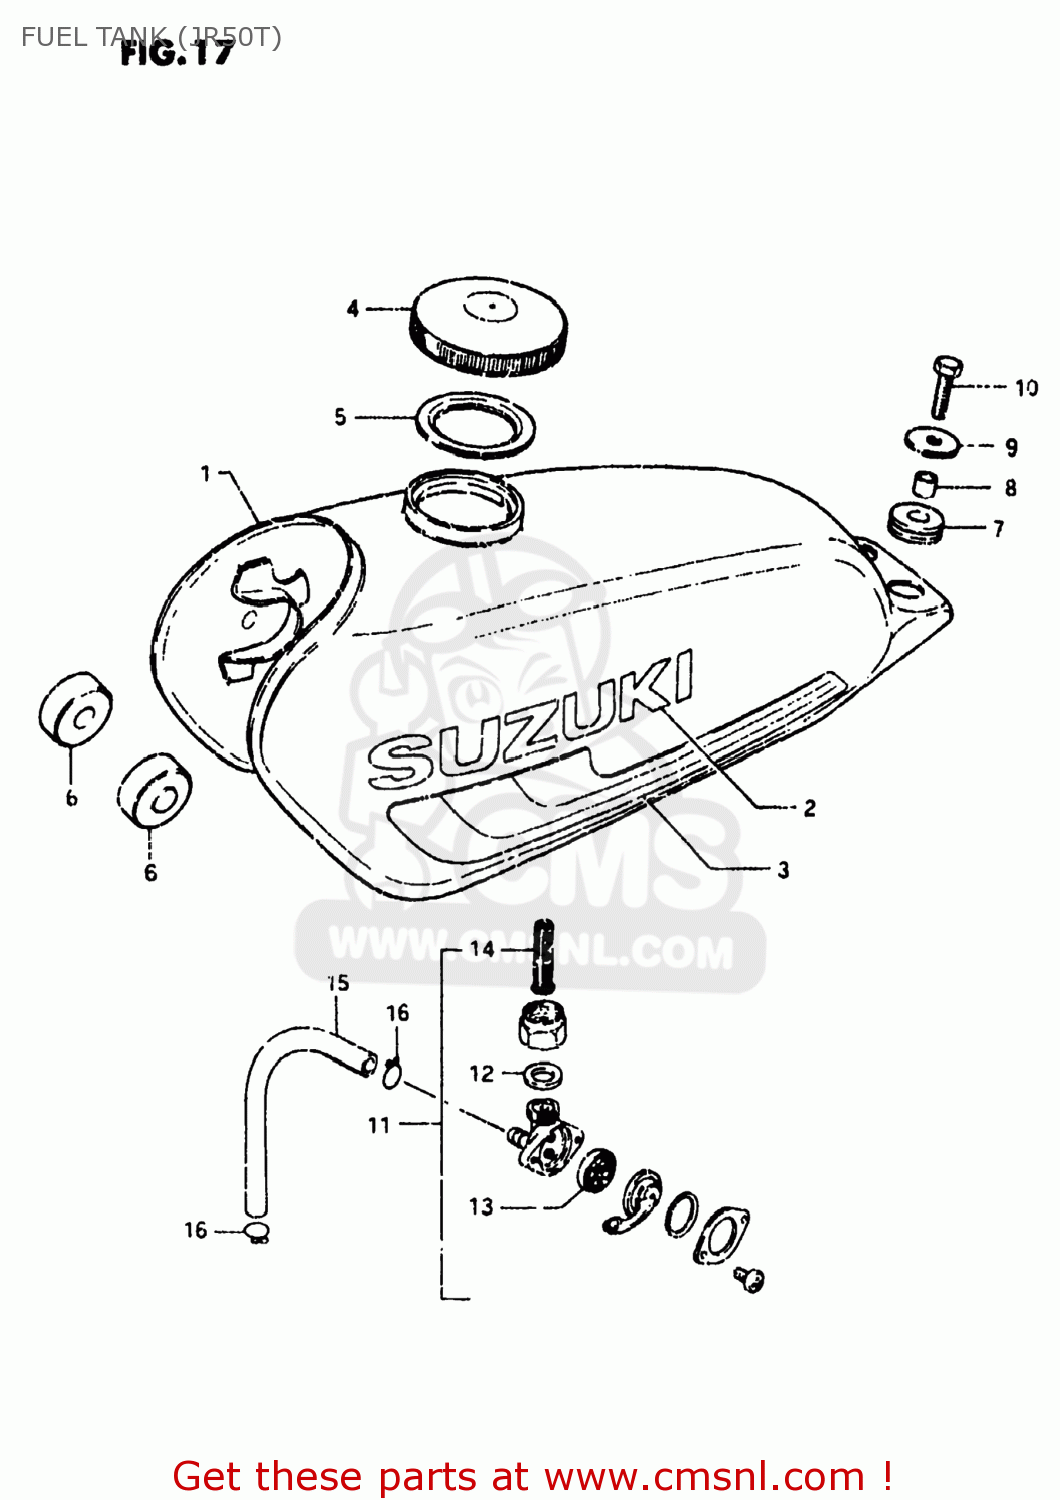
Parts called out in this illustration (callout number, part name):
1	TANK ASSEMBLY,FUEL
2	EMBLEM
3	TAPE SET,FUEL TANK
4	CAP SET,FUEL TANK
5	GASKET,CAP (NAS)
6	CUSHION
7	CUSHION
8	SPACER(6.1X9X7.5)
9	WASHER (6.5X24X1.6)
10	BOLT, UPPER
11	COCK ASSEMBLY,FUEL
12	GASKET,FUEL COCK (NAS)
13	PACKING,VALVE (NAS)
14	FILTER,FUEL
15	HOSE
16	CLIP
